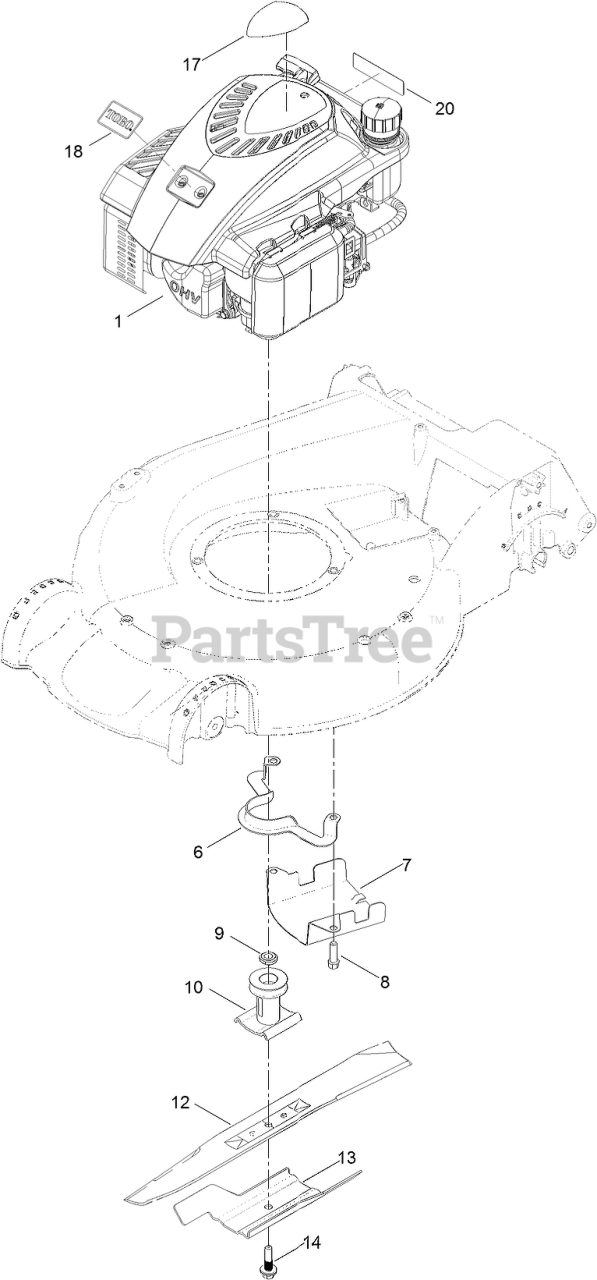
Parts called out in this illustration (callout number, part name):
1	ENGINE-1P65FC
6	GUIDE-BELT
7	SHIELD-GRASS
8	SCREW-TAPTITE
9	Spacer-Driver
10	DRIVER-BLADE
12	BLADE-RECYCLING
13	Accelerator-Blade
14	BOLT-BLADE
17	DECAL-SHROUD
20	DECAL-ARRESTER, SPARK
